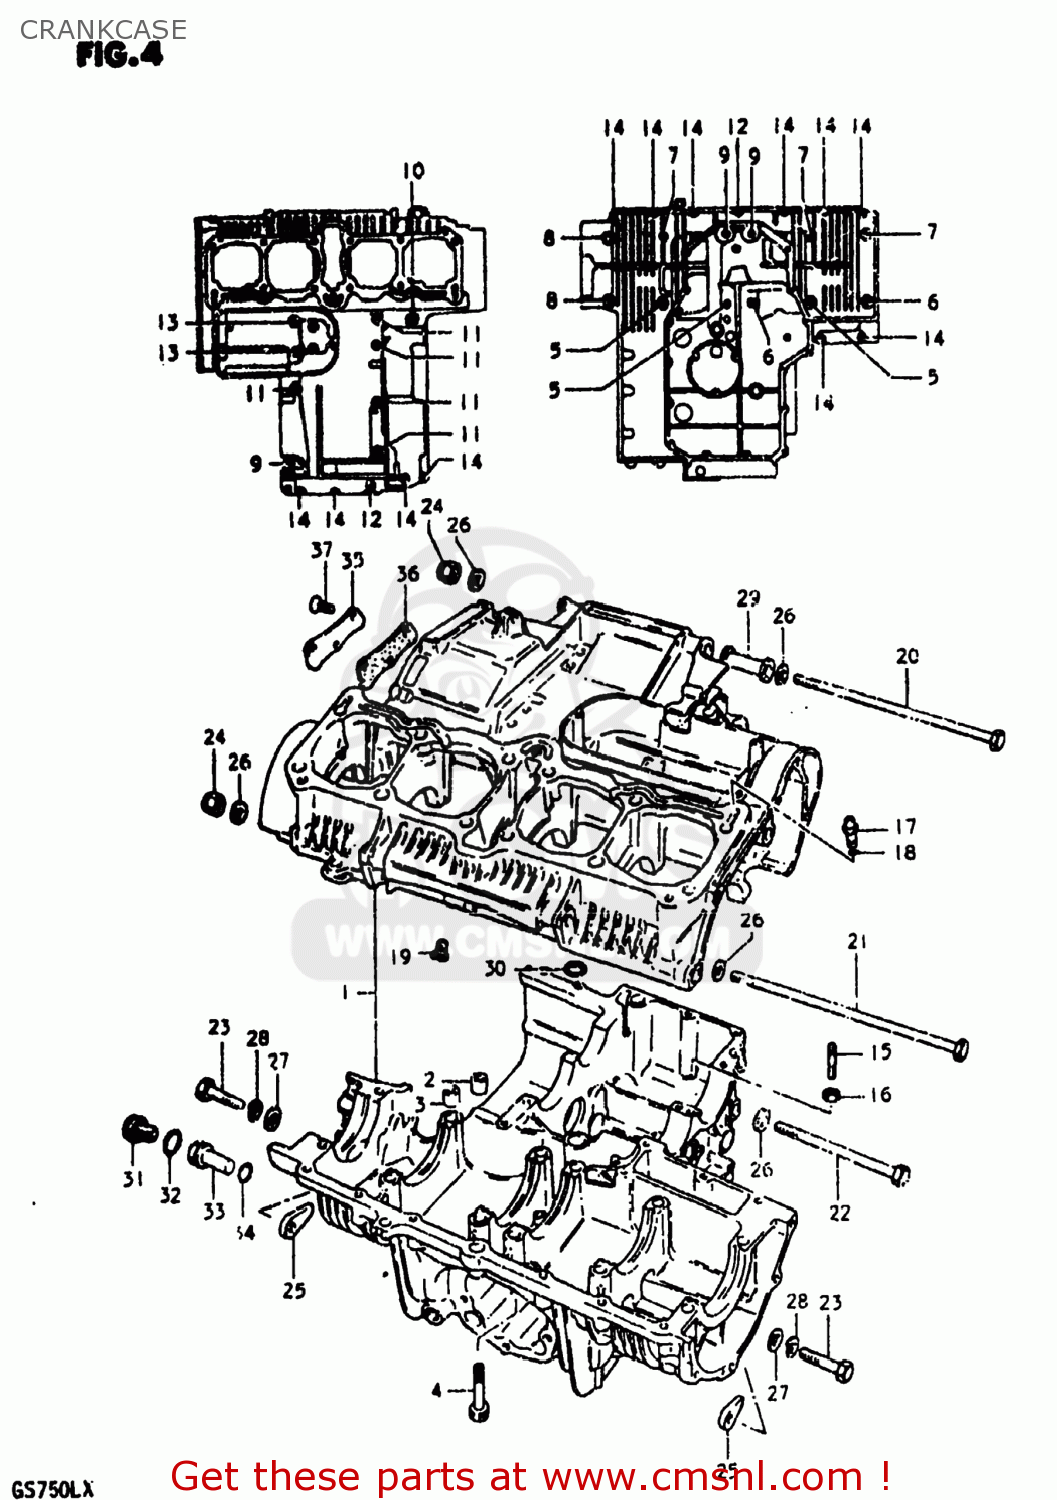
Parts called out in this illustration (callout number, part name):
1	CRANKCASE SET
2	PIN(10.4X13X22)
3	PIN (11X20)(SUS)
4	BOLT
5	BOLT(8X140)
6	BOLT
7	BOLT (8X95)
8	BOLT (8X70)
9	BOLT 8X65
10	BOLT 6X95
11	BOLT (6X80)
12	BOLT (6X60)
13	BOLT,UNDER
14	BOLT
15	STUD BOLT
16	NUT
17	JET
18	O-RING
19	JET,AIR
20	BOLT 10X230
21	BOLT 10X250
22	BOLT(10X165)
23	BOLT 10X60
24	NUT
25	NUT
26	WASHER
27	WASHER(10.5X20X3.2)
28	LOCK WASHER
29	SPACER,ENGINE MOUNT
30	O RING(D:3.2,ID:12.9)
31	PLUG
32	O RING(D:2.4,ID:17.8)
33	PIN,OIL GALLERY
34	SEAL (D:1.9 ID:9.8)
35	CAP,OIL GALLERY
36	GASKET,OIL GALLERY (MCA)
37	SCREW
